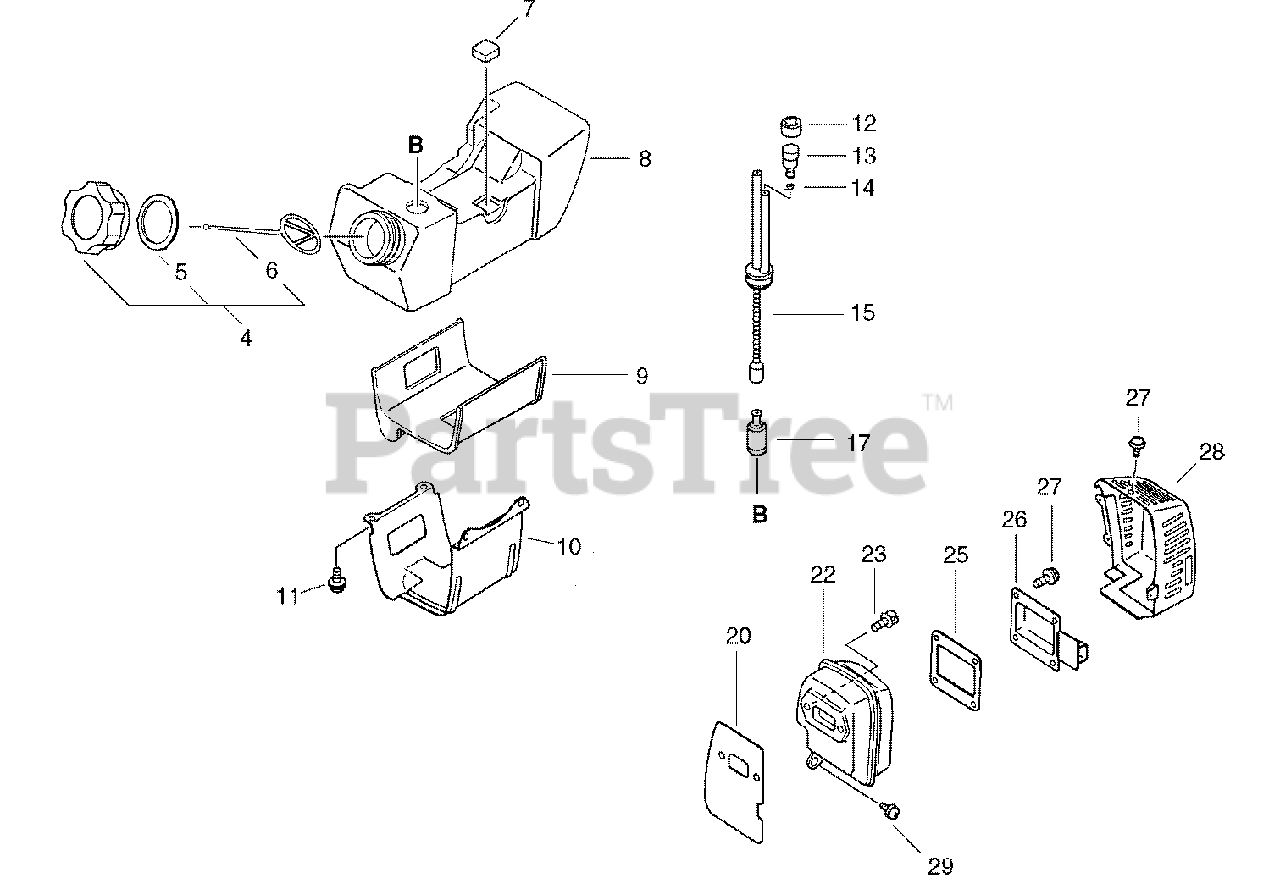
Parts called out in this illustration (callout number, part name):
4	CAP ASSY
5	GASKET, CAP
6	CONNECTOR, CAP
7	CUSHION, FUEL TANK
8	TANK, FUEL
10	BRACKET, FUEL TANK
11	SCREW - 5X14
12	COVER, VENT
13	VENT, FUEL TANK
14	CLIP - 6.5
15	FUEL PIPE ASSY
17	FILTER, FUEL
20	GASKET, EXHAUST
23	SCREW - 5X20
25	GASKET, EXHAUST
26	GUIDE, EXHAUST
27	SCREW - 4X10
28	COVER, MUFFLER
29	SCREW - 5X14
